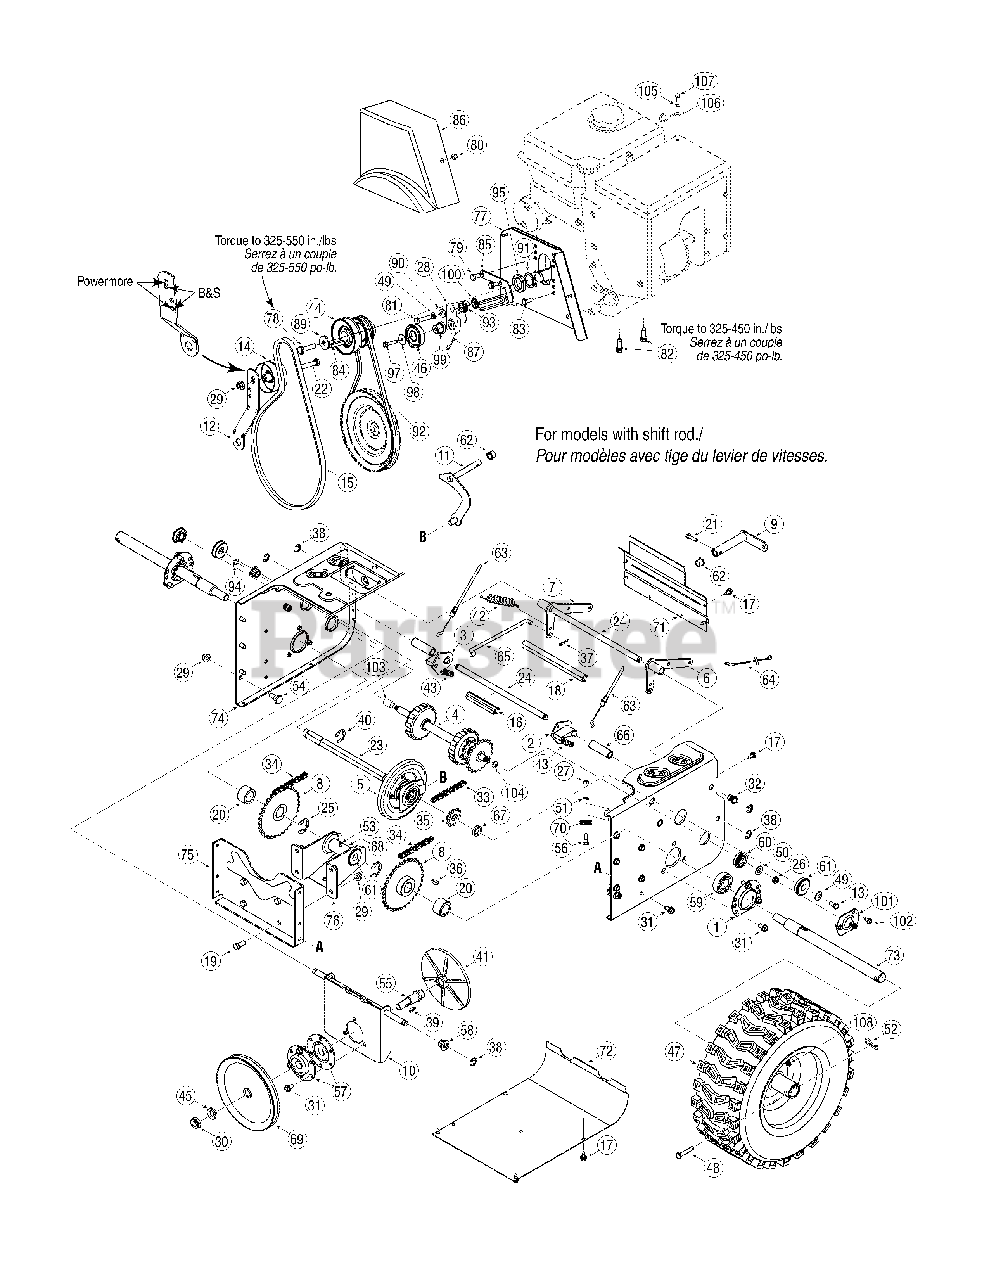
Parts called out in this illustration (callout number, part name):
1	Bearing Housing
2	LH Dog Assembly
3	RH Dog Assembly
4	Steering Shaft Assembly
5	Wheel Ass’y Bearing 6.0" OD
5	Friction Wheel Bonded
5	Hex Wash. Hd. TT Scr. 1/4-14 x .625
6	Actuator Auger Bracket Ass’y
7	Actuator Drive Bracket Ass’y
8	32T Sprocket Ass’y
9	Shift Arm Ass’y
10	Friction Drive Support
11	Shift Ass’y Rod
12	Auger Idler Bracket
13	Hex L-Bolt 5/16-18 x .62
14	Flat Idler Pulley
15	V-Belt 4L x 44.6" Lg.
16	Spacer .51 ID x 3.66" Lg.
17	Hex Wash Hd TT Scr. 1/4-20 x .625
18	Spacer .51 ID x 7.895" Lg.
19	Hex Hd. C-Sunk Scr. 3/8-16 x .880 Gr. 5
20	Spacer 1.0 ID x 1.5" Lg.
21	Hex Bolt 1/4-20 x 1.00
22	Hex Screw 3/8-16 x 1.75
23	Hex Drive Shaft
24	Actuator Shaft
25	Retaining Ring
26	Hex Nut 3/8-24
27	Hex Nut 1/4-28
28	Drive Idler Bracket
29	Flange L-Nut 3/8-16 Gr. F Nylon
30	Hex Jam Locknut 5/8-18 Gr. 5 Nylon
31	TT Screw, 5/16-18 x .75
32	Nut In sert 3/8-16 UNC
33	#41 Chain 1/2" pitch x 36 links- End less
34	#420 Chain 1/2" pitch x 40 links-End less
35	10T Sprocket #41 x .500
36	Wood ruff Key
37	Int. Cotter Pin 5/16 DIA
39	No. 61 Hi-Pro Key 3/16 x 5/8
40	Retaining Ring E-Type .875 dia.
41	Aluminum Drive Plate
42	Idler Extension Spring
43	Extension Spring .47 OD x 2.03 Lg.
44	Pulley, Dbl (w/357 cc Powermore engine)
45	Lockwasher 5/16 ID
46	Idler Pulley Ass'y
49	Cupped Washer .345 ID x .88 OD x .06
50	Flat Washer .385 ID x .87 OD x .06
51	L-Wash 1/4 ID
52	Int. Cotter Pin
54	Shld. Scr. .500 Dia. x .335" Lg.
55	Drive Plate Spin dle
56	Hex Shld.Scr.1/4-28 x .375
57	Bearing Hsg. Ass’y.
58	Hex Flange Bearing
59	Self Aligning brg. 1.0 ID
60	Ball Bearing .5625 ID x 1.3750 x .4375
61	Ball Bearing w/snap ring
62	Flange Bushing .500 ID x .627 OD
63	Steering Cable
64	Auger Idler Cable
65	Drive Clutch Rod
66	Split Spacer 1/2 x 5/8 x 2.69
67	Spacer .625 ID x 1.0 OD x .23
68	Spacer .6725ID x 1.125OD x 2.485
69	1/2" "V" Pulley .625 ID x 7.50 OD
70	Cable Guide Roller
71	Upper Frame Cover
72	Lower Frame Cover
73	Axle .995 x 12.6" Lg. (28")
73	Axle.995 x 14.10" Lg (30" & 33")
75	Frame Support Bracket
76	Axle Brg. Support Bracket
77	Belt Cover Bracket
78	Hex Screw 3/8-24 x 1.25 Gr. 8 (Powermore)
79	Hex Screw 5/16-24 x .75 Gr. 5
80	Hex Wash HD S-Tapp Scr 5/16-18 x .50
81	Hex HD. Cap Scr. 5/16-24 x 1.5 Lg. Gr. 5
82	Hex Wash HD Tap Scr 3/8-16 x 1.00
83	Shoulder Screw .50 x .145: 5/16-24
84	Square Key 1/4 x 1/4 x 1.50" Lg.
85	Belt Keeper Bracket
87	Torsion Spring .850 x 3.33" Lg.
89	Flat Washer .406 ID x 1.25 OD x .160
90	Shoulder Spacer .3175 x .5 x .094
91	Spacer 1.155 ID x 1.5 OD x 0.150 (w/Powermore)
92	V-Belt 3/8 x 36.68" Lg. (Powermore)
93	Shoulder Spacer .340 x 1.0
94	Speed Nut .50
95	Spacer 1.004 x 1.375 x .25 (w/357 cc Powermore)
97	Hex Bolt 1/4-20 x 1.25
98	Flat Washer .265 ID x 1.0 OD x 0.030 HT
99	Shoulder Spacer
100	Push on Nut
101	Bearing Retaining Bracket
102	Hex Wash S-Tapp Scr 1/4-20 x .50
103	Spacer .566 ID x .87 OD x 1.25
104	Spacer .566 ID x .87 OD x 0,190
105	Flat Washer .330 ID x .630 OD x .0635
107	Hex Hd. Cap Scr. MB-1.25:20 Gr. 8
